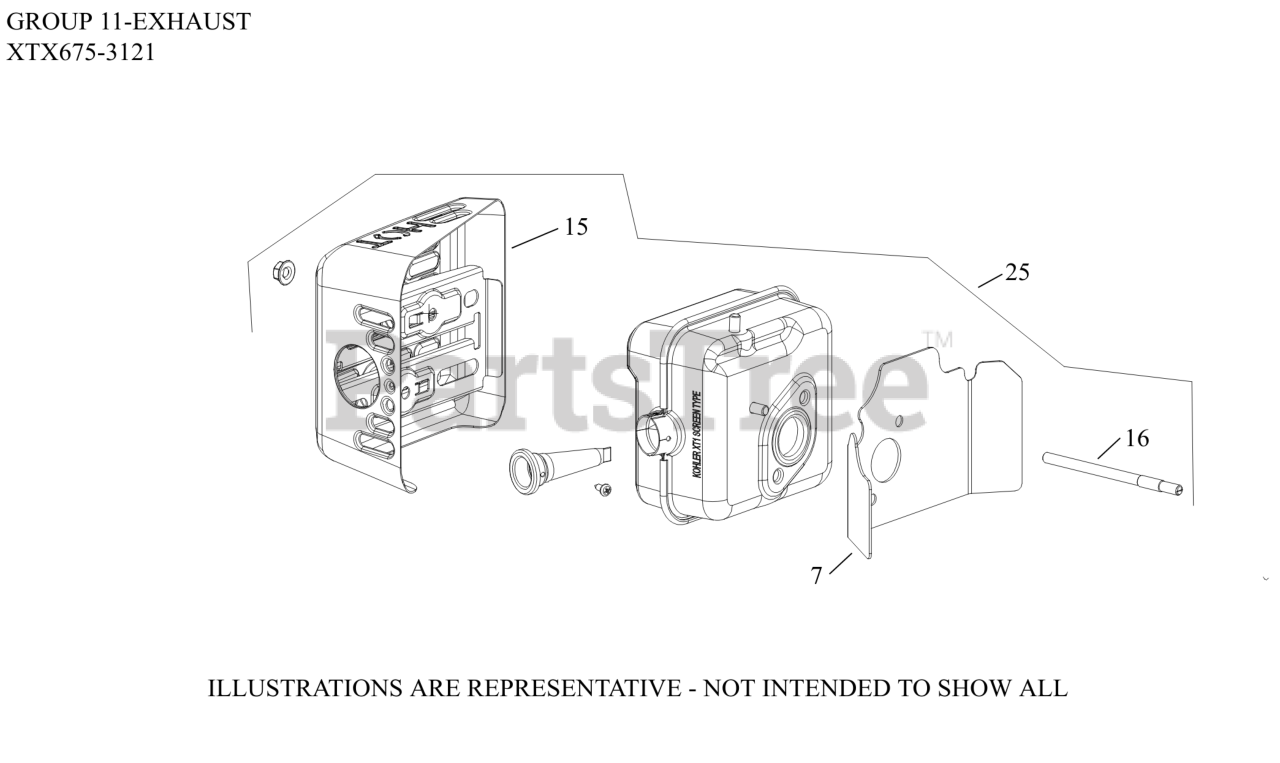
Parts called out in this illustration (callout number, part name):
7	GASKET, MUFFLER (HEAT DEFLECTOR)
15	GUARD, MUFFLER ASSEMBLY
16	STUD, EXHAUST (M6)
25	KIT, MUFFLER
